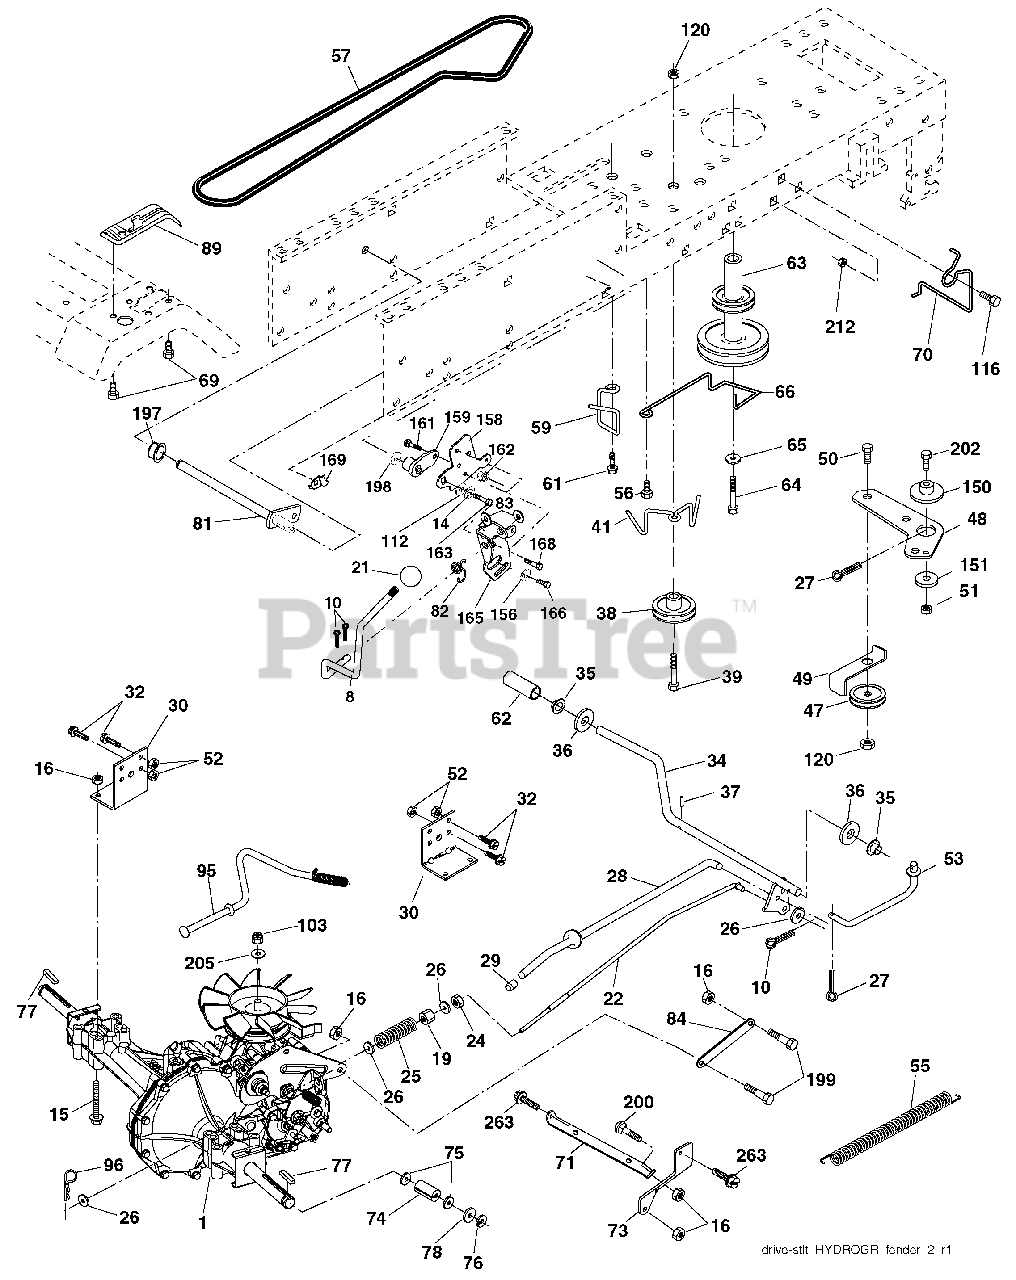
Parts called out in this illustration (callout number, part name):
8	Rod Shift
10	Pin Cotter 1/8 X 1
14	Washer Lock 1/4
15	Bolt Hex FLGHD 5/16-18 Gr. 5 unc
16	Nut Lock Hex w/ins 5/16-18 unc
19	Nut Lock Hex w/wsh 3/8-16 unc
21	Knob
22	Rod Brake
24	Nut
25	Spring Rod Brake
26	Washer 13/32 x 13/16 x 16 Ga.
27	Pin Cotter 1/8 x 3/4
28	Rod Brake Parking
29	Cap Brake Parking
30	Bracket Transmission
32	Bolt Hex Hd 5/16-18 unc x 3/4
34	Shaft Foot Pedal
35	Bearing Nylon
36	Washer
37	Pin Roll
38	Pulley Idler Composite
39	Bolt
41	Keeper Belt Idler
47	Pulley Idler V-Belt
48	Bellcrank Clutch Grnd Drustl
49	Retainer Belt
50	Bolt Carr. Sh. 3/8-16 x 1-1/2 Gr. 5
51	Nut
52	Nut Crownlock 5/16-28
53	Link Clutch
55	Spring Return Clutch
56	Screw 3/8-16 x 1-1/4
57	V-Belt Drive
59	Keeper Belt Center
61	Screw 3/8-16 x .875
62	Cover Pedal
63	Engine Pulley
64	Bolt Hex 7/16-20 x 4 x Gr. 5-1.5
65	Washer
66	Keeper Belt Engine Hydro
69	Screw Hex wsh HiLo 1/4 x 1/2 unc
70	Guide Belt Mower Drive RH
71	Strap Torque, LH
73	Strap Torque, RH
74	Spacer Axle
75	Washer 25/32 x 1 1/4 x 16 Ga.
76	Ring, E
77	Key Square
78	Washer 25/32 x 1-5/8 x 16 Ga.
81	Shaft Asm Cross
82	Spring Torsion
83	Washer 17/32 x 3/4 x 16 Ga.
84	Link Transaxle
89	Console Shift
95	Control Asm Bypass Hydro
96	Retainer Spring 1"
103	Nut, Hex Jam Top Lock 1/2-20 unf
112	Washer 9/32 x 3/4 x 10 Ga.
116	Bolt 3/8-16 x 1
120	Bolt Hex 3/8-16 x 1-1/2
150	Spacer Retainer
151	Washer 13/32 x 2 x 10
156	Washer 5/16 x 1.0 x 1.25
158	Bracket Shift Mount
159	Hub Tapered Flange Shift
161	Bolt Rdhd Sqnk 1/4-20 x 3/4 Gr. 5
162	Nut Crownlock 1/4-20 unc
163	Bolt Hex Fin 1/4-20 x 1
165	Bracket Pivot Lever
166	Screw 5/16-18 x 1.0 x .125
168	Bolt Shoulder 5/16-18 x .561
169	Plate Fastening
197	Nyliner Snap-In 5/8
198	Washer Nyliner 7/8 ID x .105 HYD
199	Bolt Shoulder 5/16-18 unc
200	Bolt Rdhd Sqnk 5/16-18 unc x 1
202	Bolt RdHd 3/8-16 unc x 1-1/2 Gr. 5
205	Washer 17/32 x 1 x 16 Ga.
212	Nut Hex flange Lock
263	Screw 3/8-16 x .75
